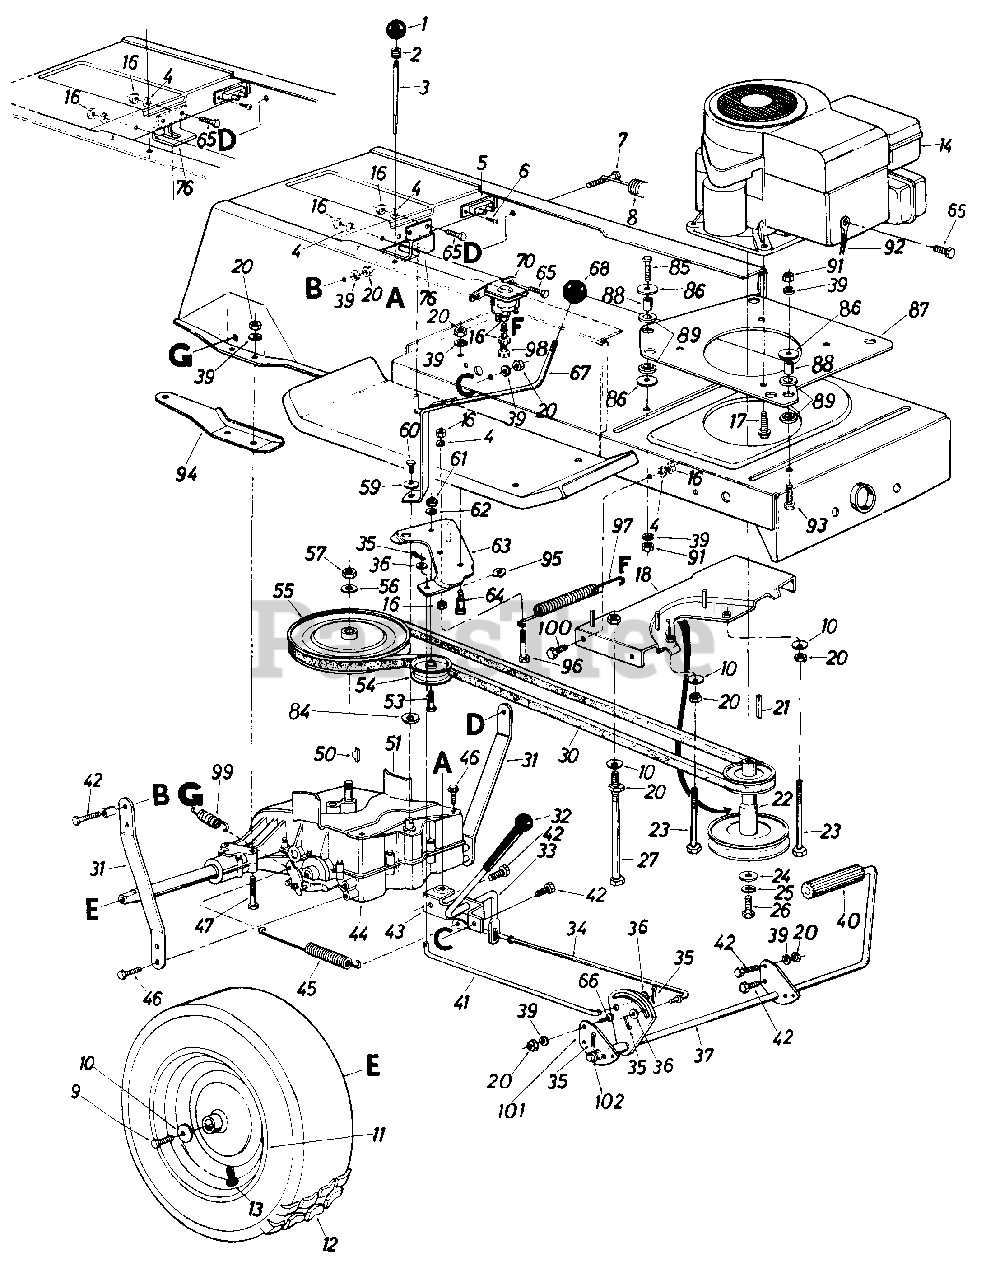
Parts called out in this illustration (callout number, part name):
1	Ball Knob 1/4-20 Thd.
2	Compression Spring .30" O.D. x 1.00" Lg.
3	Brake Lockout Rod
4	L-Wash. 1/4" I.D.
5	Circuit Breaker
6	Truss Hd. Phil. Scr. #10 x 1/Z'l Lg
7	Hex Bolt 5/16-18 x 1.25" Lg.
8	Ext. Spring .99" O.D. x 11"
9	Hex Bolt 5/16-24 x .75" Lg.
10	Bell-Wash. 5/16" I.D.
11	Rear Wheel Rim Only
12	Rear Wheel Ass'y. Comp.
14	Engine
16	Hex Nut 1/4-20 Thd.
17	Hex Bolt 3/8-16 x 1.25" Lg.
18	Belt Guard Brkt. Ass'y.
20	Hex Nut 5/16-18 Thd.
21	Sq. Key 1/4 X 1/4 X 2.0
22	Two Step Engine Pulley
23	Hex Bolt 5/16-18 x 5.25" Lg.
24	Fl-Wash. 7/16" I.D. x 1.25" O.D. x .180
25	L-Wash. 7/16" I.D.
26	Hex Bolt 7/16-20 x 1.50" Lg.
27	Hex Bolt 5/16-18 x 5.25
30	"V"-Belt "A" Glass 85" Lg. Bare Back
31	Transaxle Brace
32	Grip
33	Hill Holder Brake Handle
34	Brake Rod
35	Cotter Pin 3/32" Dia. x l.O"
36	Fl-Wash. .344" I.D. x .625"
37	Brake/Clutch Pedal Ass'y.
39	L-Wash. 5/16" I.D.
40	Foot Pedal Pad
41	Clutch Rod
42	Hex Bolt 5/16-18 x .75" Lg.
43	Brake Lock and Handle Support Brkt.
44	Transaxle Complete
45	Ext. Spring .590" O.D. x 7.08" Lg.
46	Hex Wash. Hd. AB-Tap Scr. 5/16 x .62" Lg.
47	Hex Bolt 5/16-18 x 2.50"
50	#4 Hi-Pro Key 3/32 x 5/8" Dia.
51	Belt Keeper
53	Hex Bolt 3/8-16 x 1.50" Lg.
54	Flat Idler Pulley 3/8" I.D. x 2.75 O.D.
55	Transaxle Pulley
56	L-Wash. 1/2" I.D.
57	Hex Nut 1/2-20 Thd.
59	Bell-Wash. .26" I.D. x .75"
60	Hex Bolt 1/4-28 x .62" Lg.
61	Hex Nut 3/8-16 Thd.
62	L-Wash. 3/8" I.D.
63	Idler Brkt. Ass'y
64	Shld. Scr. .437" Dia. x 1.80" Lg.
65	Hex Bolt 1/4-20 x .62" Lg.
67	Shift Lever Ass'y.
68	Ball Knob 3/8-16 Thd.
70	Solenoid
76	Shift Lever Pivot Brkt.
84	Special Wash. 1.00" O.D.
85	Hex Bolt 5/16-24 x 1.25"
86	Fl-Wash. 1.25" O.D. x .320" I.D.
87	Engine Mounting Plate
88	Spacer
89	Engine Mounting Grommet
91	Hex Nut 5/16-24 Thd.
92	Electric Ground Wire
93	Hex Bolt 5/16-24 x 1.50"
94	Transaxle Support Brkt. R.H.
95	Wave Wash.
96	Hex Bolt 1/4-20 x 2.50" Lg.
97	Ext. Spring
98	Hex Bolt 1/4-20 x 2.50" Lg.
99	Brake Return Spring
100	Hex Bolt 1/4-28 x .75 Lg. (Grade 5)
101	Pedal Bracket
102	Fl-Wash. .63" I.D. x 1.0" O.D.
